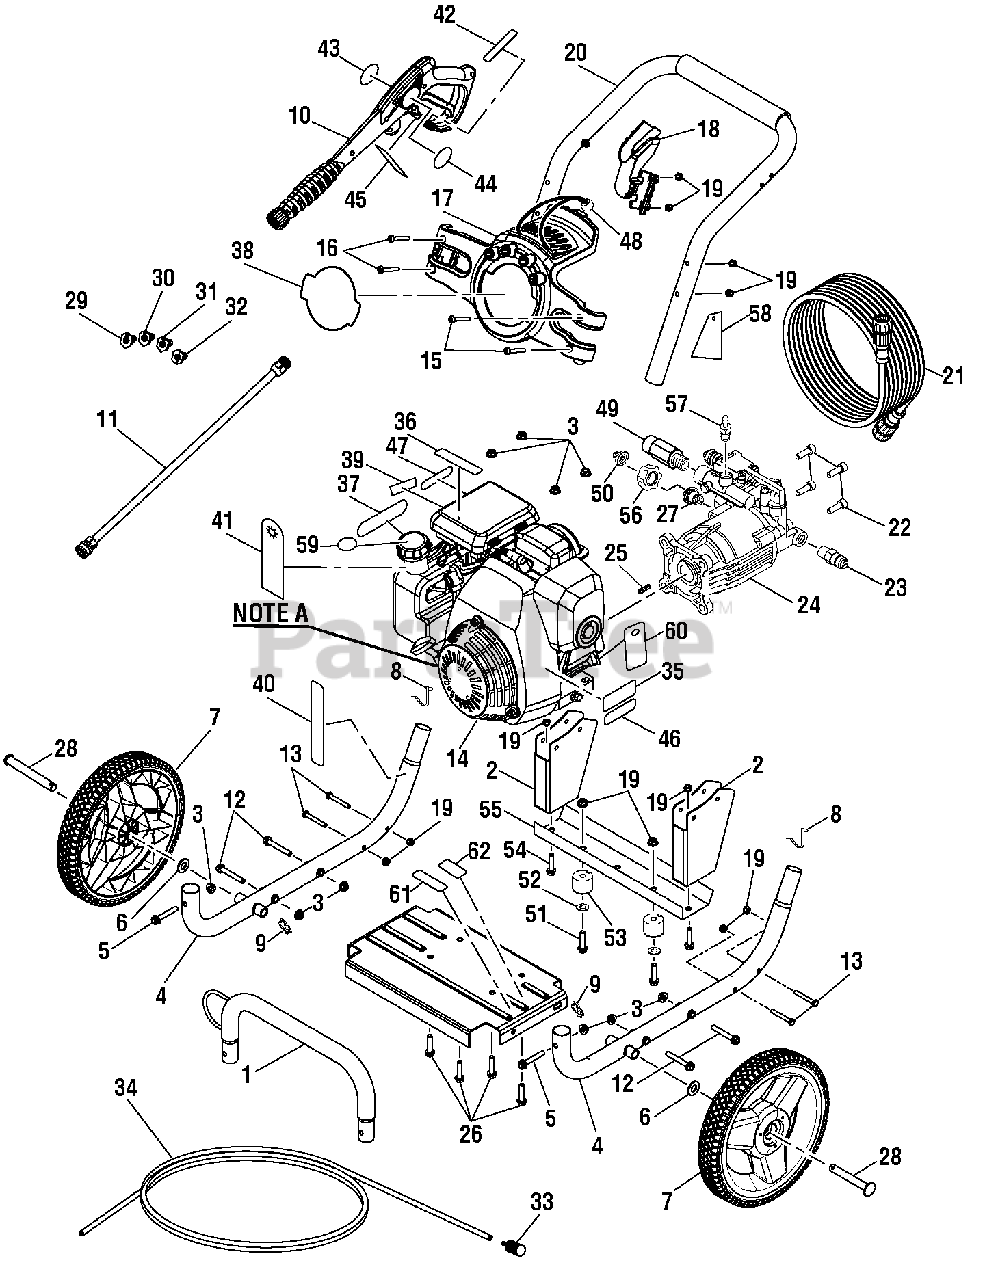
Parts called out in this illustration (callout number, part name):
1	Front Frame
2	Rear Foot
3	Hex Nut (M8 x 1-1/4 in.)
4	Main Frame Assembly
5	Bolt (M8 x 45 mm, Flange Hd.)
6	Washer (1/2 in.)
8	Lock Button w/Spring Clip
9	Ring Clip
10	Trigger Handle Assembly
11	Extension Wand
12	Bolt w/Washer (M8 x 55 mm, Hex Hd.)
13	Bolt (1/4-20 x 52 mm Hex Hd.)
14	Engine
15	Screw (1/4-20 x 1.85 in., T30 Torx Hd.)
16	Screw (1/4-20 x 2.27 in., T30 Torx Hd.)
17	Hose and Nozzle Holder Assembly
18	Wand Holder
19	Lock Nut (1/4-20)
20	Handle w/Foam
21	Hose (25 ft., 3000 psi)
22	Screw (5/16-24 x 23 mm Soc Hd.)
23	Thermal Release Valve
25	Output Shaft Key (40 mm)
26	Bolt (M8 x 36 mm, Flange Hd.)
29	0deg Nozzle
30	25deg Nozzle
31	40deg Nozzle
32	Soap Nozzle
33	Detergent Injection Filter
34	Detergent Injection Tube
35	Label (Hot Surface)
36	Label (Engine Quick Start)
37	Label (Warning)
38	Label (Performance)
39	Label (E85)
40	Label (Pump Quick Start)
41	Label (Warning Hang Tag)
42	Label (Wand Rating)
43	Label (Wand Logo)
44	Label (Wand Warning)
45	Label (Warning)
46	Label (UL Fire Warning)
47	Label (Inquires)
48	Bungee Cord and Bead Assembly
49	Outlet Tube
50	Filter Screen (Pump Inlet)
51	Bolt (1/4-20 x 25 mm, Hex
52	Washer (1/4 in.)
53	Rubber Foot
54	Bolt (1/4-20 x 5/8 in.)
57	Detergent Suction Kit
58	Label (Nozzle Hang Tag)
59	Label (Do Not Mix)
60	Label (Oil Dipstick Hangtag)
61	Label (Lubricant Label)
62	Label (Add Oil)
